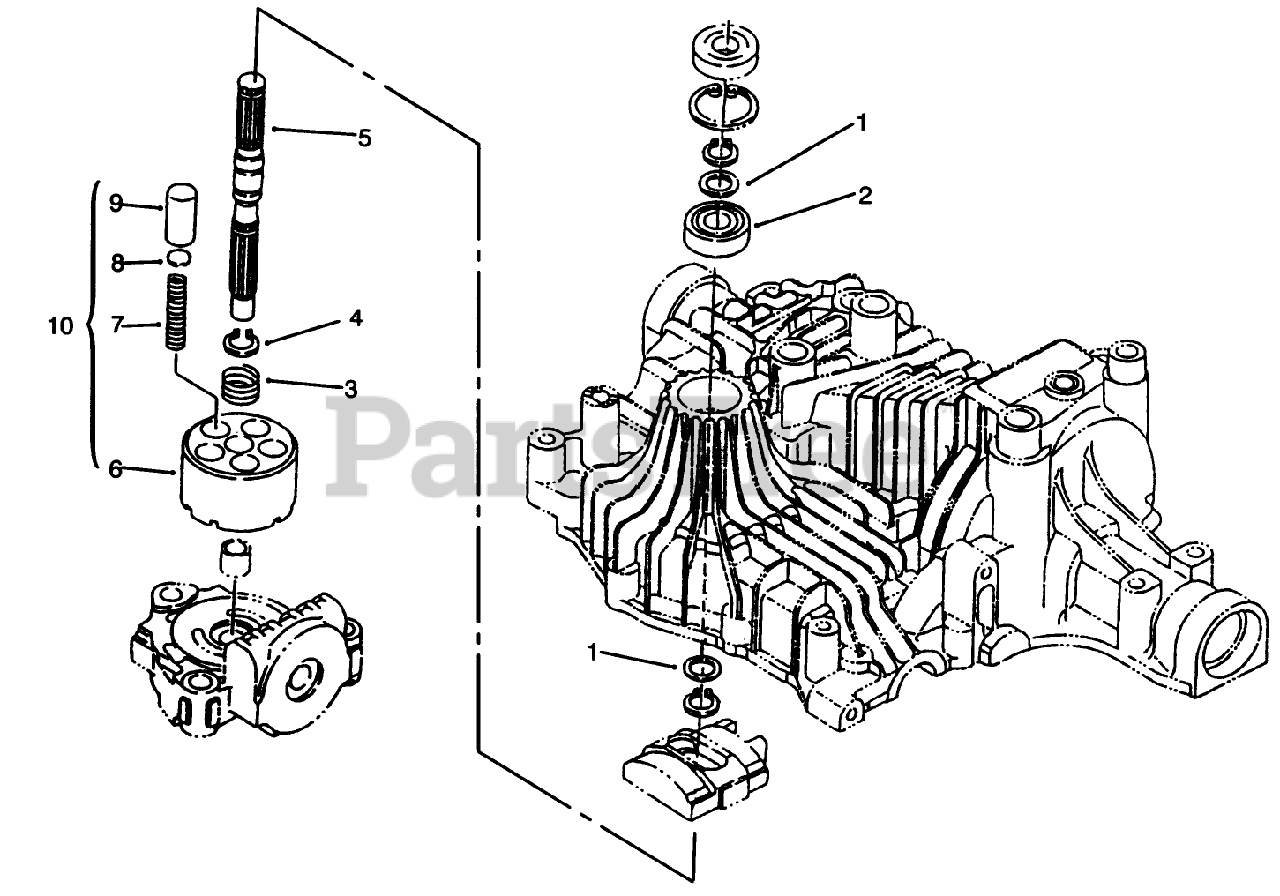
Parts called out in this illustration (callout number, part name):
2	BEARING-BALL
3	SPRING
4	RING-SNAP
10	ASM - CYCLINDER INC 6-9
